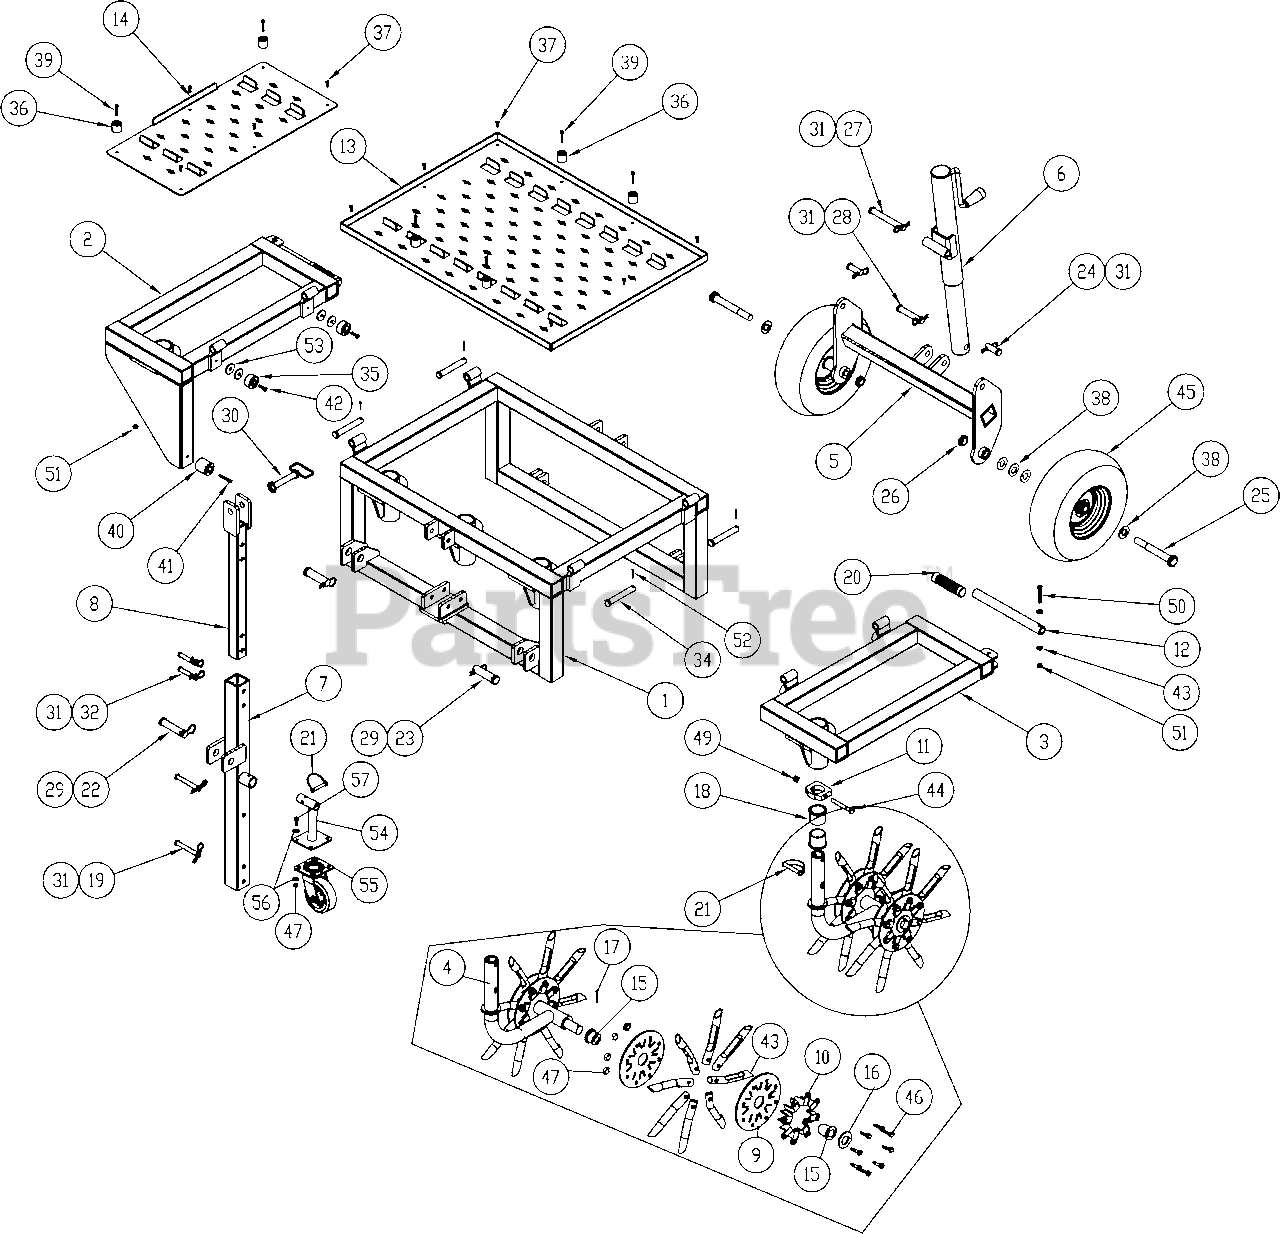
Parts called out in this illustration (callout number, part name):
1	BASE FRAME WELDMENT
2	LEFT WING FRAME WELDMENT
3	RIGHT WING FRAME WELDMENT
4	TINE AXLE WELDMENT
5	WHEEL ASSEMBLY
6	JACK ASSEMBLY
7	OUTER TOW LINK
8	INNER TOW LINK
9	TINE HUB PLATE
10	TINE HUB C-CLIP
11	ARM SWIVEL STOP
12	WING HANDLE
13	BASE LOAD PAN
14	WING LOAD PAN
15	TINE SHOULDER BUSHING
16	WASHER 1/2" FLAT
17	COTTER PIN 1/8" X 1.5"
18	TINE ARM SHOULDER BUSHING
19	CLEVIS PIN 7/16" X 3.5"
20	GRIP HANDLE 1" X 5.5"
21	LOCK PIN 3/8" X 2.5"
22	CLEVIS PIN 3/4" X 3.5"
23	CLEVIS PIN 7/8" X 3"
24	CLEVIS PIN 5/8" X 1.75"
25	SCREWCAP 3/4"-10 X 5 1/2" HCS ZP
26	NUT JAM 3/4"-10
27	CLEVIS PIN 5/8" X 5"
28	CLEVIS PIN 5/8" X 3.5"
29	COTTER HAIR PIN 1/8" FOR 3/4 TO 7/8"
30	HITCH PIN 5/8" X 4" W/LYNCH PIN
31	COTTER HAIR PIN 1/8" FOR 7/16 TO 5/8
32	CLEVIS PIN 7/16" X 2.5"
33	TINE 3/4" CLOSED SPOON 14 GA.
34	CLEVIS PIN 5/8" X 4"
35	RUBBER BUMPER 1.5" X .75" THK
36	RUBBER BUMPER 1.0" X 1.0" THK
37	SHCS 10-32 X 1/2"
38	WASHER 3/4" SAE
39	SHCS 10-32 X 1.25"
40	RUBBER BUMPER 1.5" X 1.5" THK
41	SHCS 1/4"-20 X 1.5"
42	SHCS 1/4"-20 X .75"
43	BELLEVILLE WASHER .25 X .69" THK
44	SCREWCAP 3/8"-16 X 3" HCS ZP
45	WHEEL 13"
46	BOLT HEX HEAD 5/16"-18 X 1 3/4
47	NUTLOCK 5/16"-18
49	NUTLOCK 3/8"-16 HEX ZP
50	SCREWCAP 1/4"-20 X 2" HCS ZP
51	NUTLOCK 1/4"-20 HEX ZP
52	COTTER PIN 1/8" X 1"
53	WASHER FENDER 5/16"
54	TRANSPORT WHEEL STAND
55	CASTER 5" DIA X 2"
56	WASHER 5/16" FLAT
57	SCREWCAP 5/16"-18 X 1" GR 5 HCS ZP
